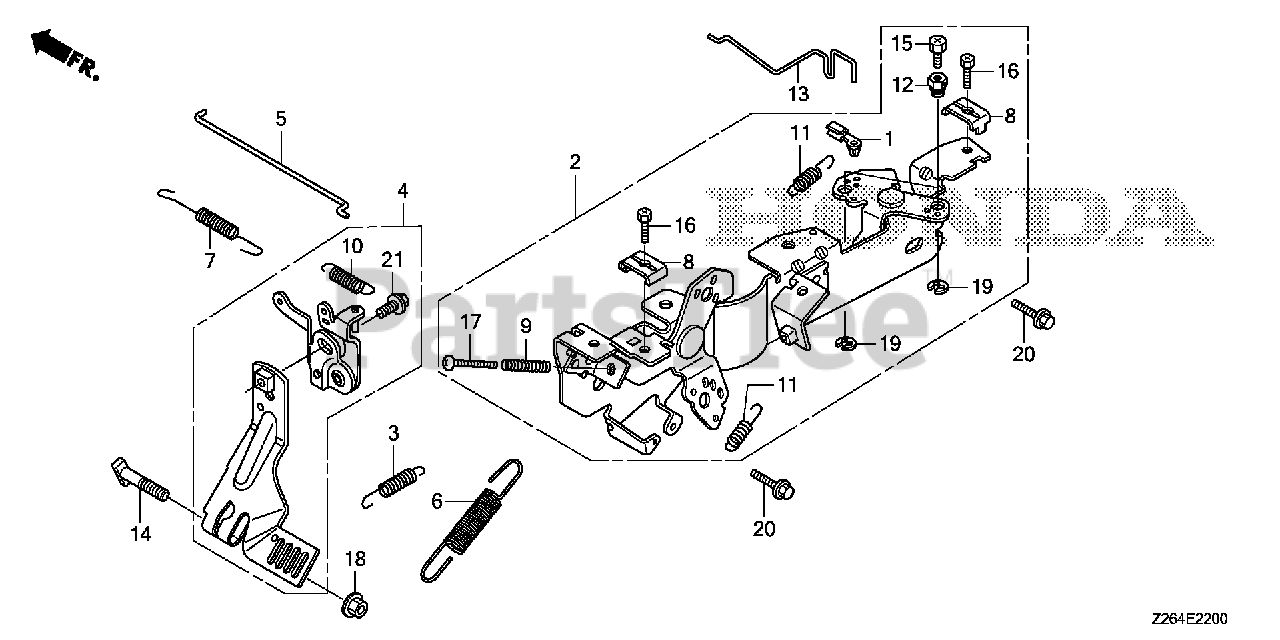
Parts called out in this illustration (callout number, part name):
1	JOINT, ROD
2	CONTROL ASSY.
3	SPRING, STARTER
4	ARM, GOVERNOR
5	ROD, GOVERNOR
6	SPRING, GOVERNOR
7	SPRING, THROTTLE RETURN
8	HOLDER, CABLE
9	SPRING, CONTROL ADJUSTING
10	SPRING, RETURN
11	SPRING, CABLE RETURN
12	HOLDER, WIRE
13	ROD, CHOKE CONTROL
14	BOLT, GOVERNOR ARM
15	BOLT, RECESSED (4X6)
16	BOLT, RECESSED (5X16)
17	SCREW, PAN (5X40)
18	NUT, FLANGE (6MM)
19	E-RING (5MM)
20	BOLT, FLANGE (6X14)
21	BOLT, FLANGE (6X10)
